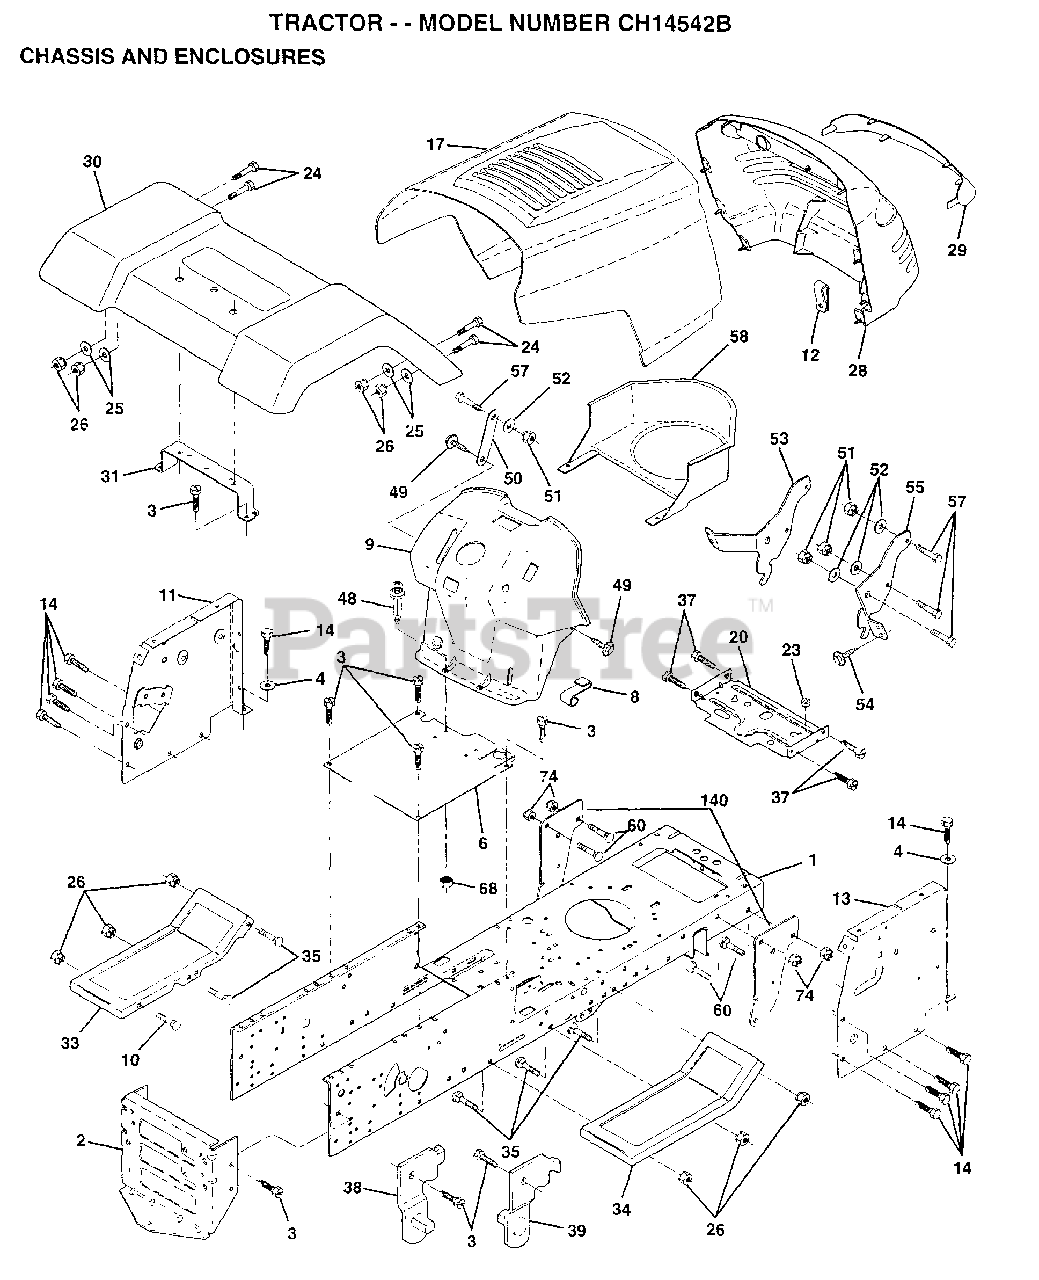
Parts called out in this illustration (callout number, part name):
1	CHASSIS WLDMT 11G
3	SCREW
4	WASHER
8	"CLIP,INSULATOR"
11	PANEL.DASH.LH.
12	CLIP.TINNERMAN
13	PANEL.DASH.RH
14	SCREW LT
20	PLATE.MTG.BTRY.TK
24	BOLT
25	WASHER
26	NUT
29	LENS GRILLE
31	BRKT FENDER
33	FOOTREST.LH.LT/GT
34	FOOTREST.RH.LT/GT
35	BOLT
37	SCREW LT
38	BRACKET ASM LH
39	BRACKET ASM RH
48	RIVET.PUSH.PLATE
49	SCREW HEX CRT
50	BRACE SUPT DASH
51	NUT
52	WASHER
53	BRACKET.GRILLE.LH
55	BRACKET.GRILLE.RH
58	AIR DUCT
60	BOLT
68	NUT
